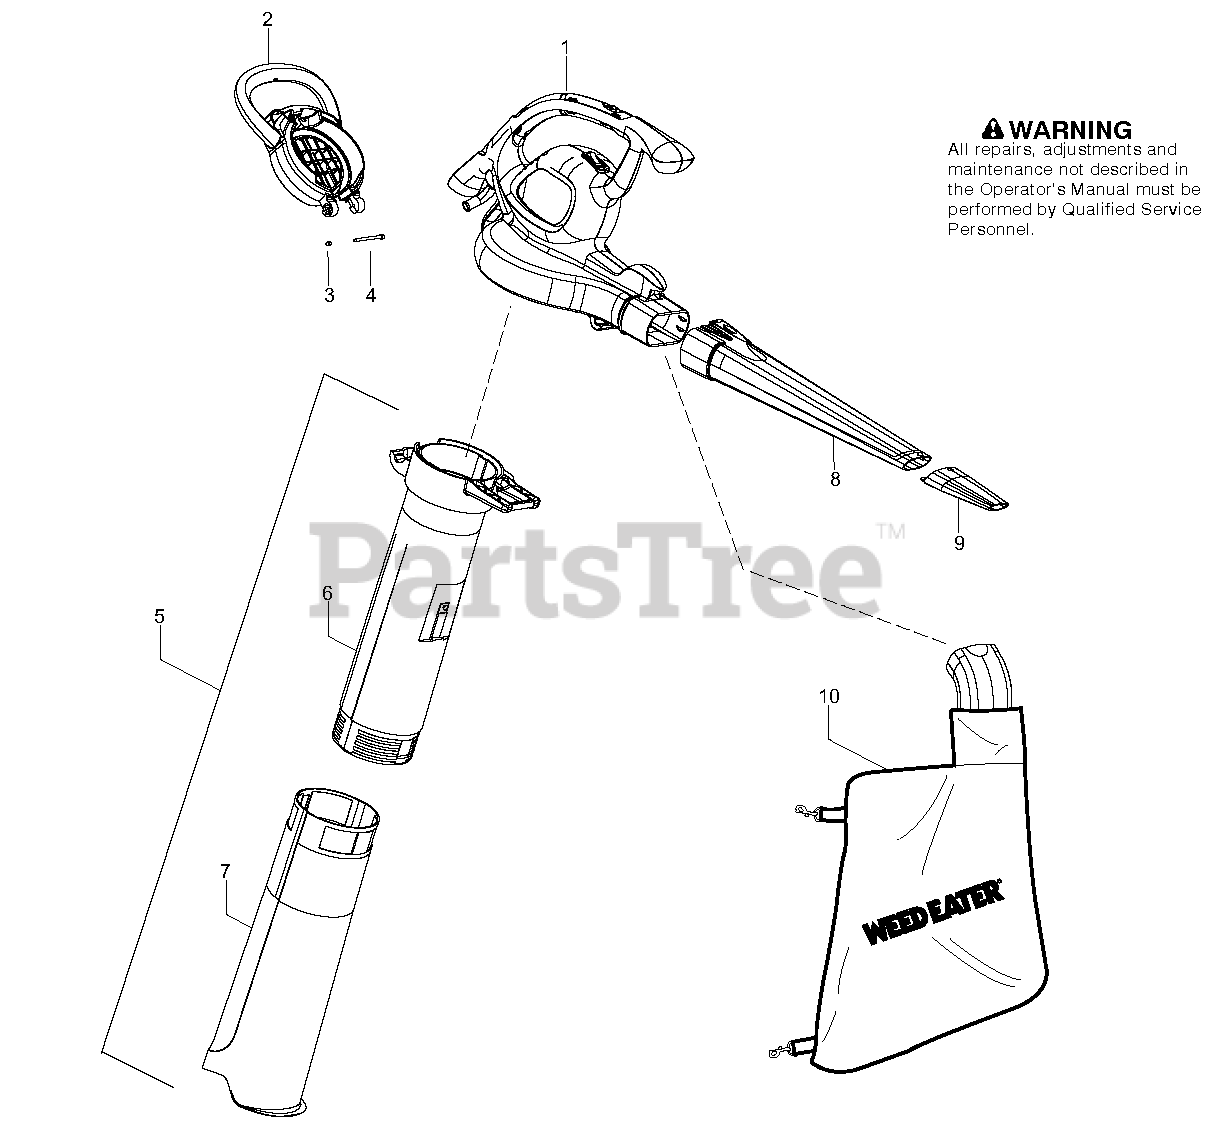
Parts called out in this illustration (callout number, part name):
2	HANDLE ASSIST VAC DOOR
3	NUT HINGE
4	SCREW HINGE
5	KIT UPPER/LOWER VAC TUBE
6	TUBE UPPER VAC
7	TUBE LOWER VAC
8	TUBE BLOWER
9	NOZZLE CONCENTRATOR
10	ASSY VAC BAG
